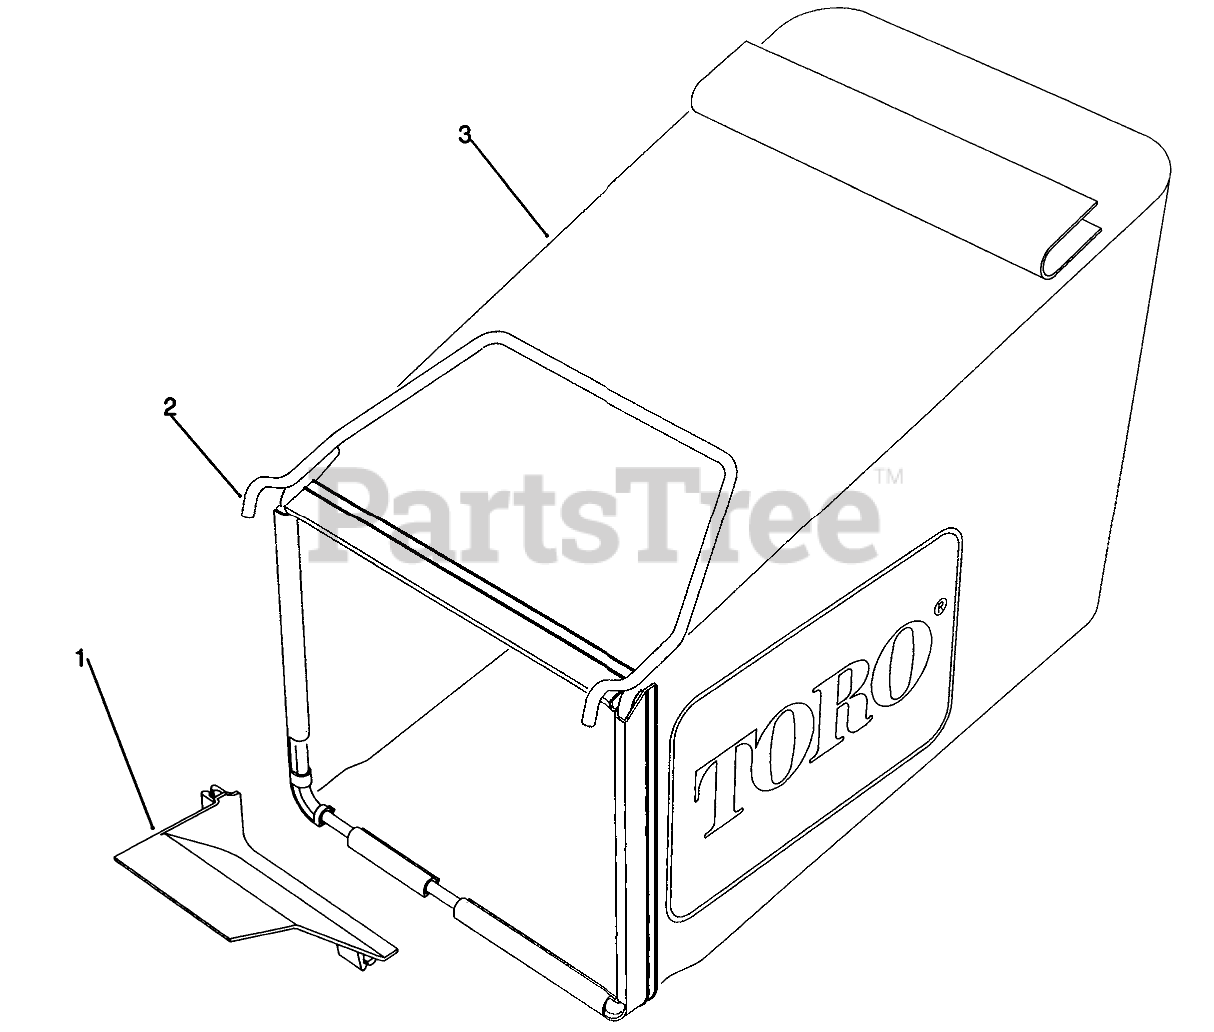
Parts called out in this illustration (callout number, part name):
1	BAG RAMP
2	FRAME WA
3	GRASS BAG REAR EMPTY
